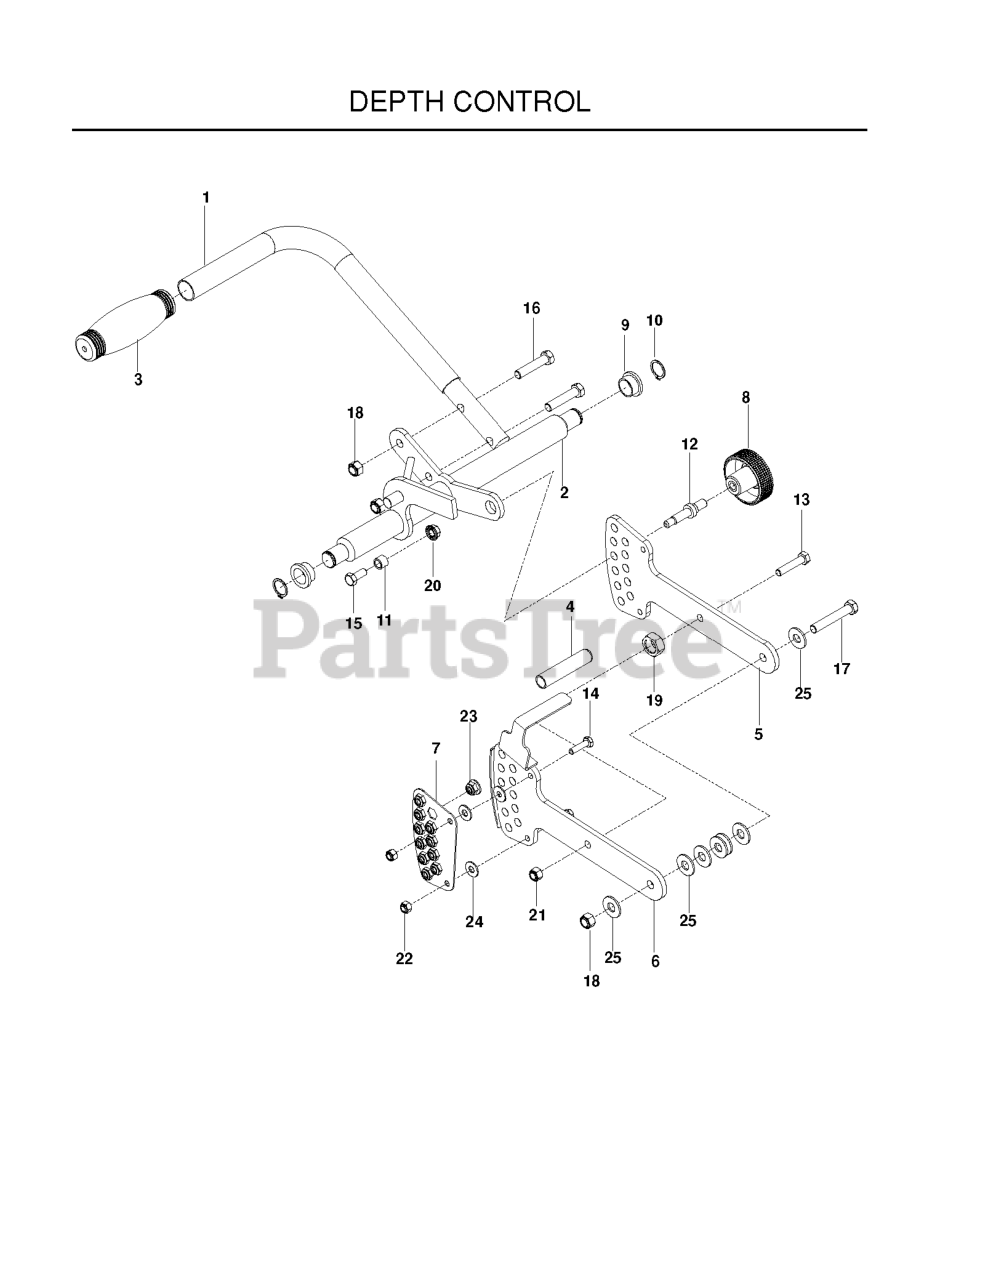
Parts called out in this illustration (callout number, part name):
1	HANDLE D.O.C. GREY
2	RP.WLDMT - D.O.C. SHAFT, GREY
3	GRIP HANDLE
5	ADJUSTER D.O.C., GREY
6	ADJUSER WLDMT RH, GREY
7	PLATE-ADJUSTER NUT, GREY
8	KNOB
9	BEARING - FLANGE
10	SNAP RING - .75
12	ADJUSTER, STUD
13	CAPSCREW 5/16 X 1/1/2 HEX HEAD
14	HCS 1/4 X 1
15	HCS 5/16C X 3/4
16	HCS 3/8-16 X 1 3/4 GR5
17	HCS 3/8C X 2 1/4
18	NUT 3/8-16 NYLOC
19	NUT 5/8F HEX
20	NUT 5/16C WHIZ
21	NUT 5/16 NYLOC
22	NUT.1/4-20.HEX.NYLOC.ZD
23	5/16-18 NYLOC FLANGE NUT
24	WASHER 1/4 FLAT
25	WASHER 3/8 FLAT
